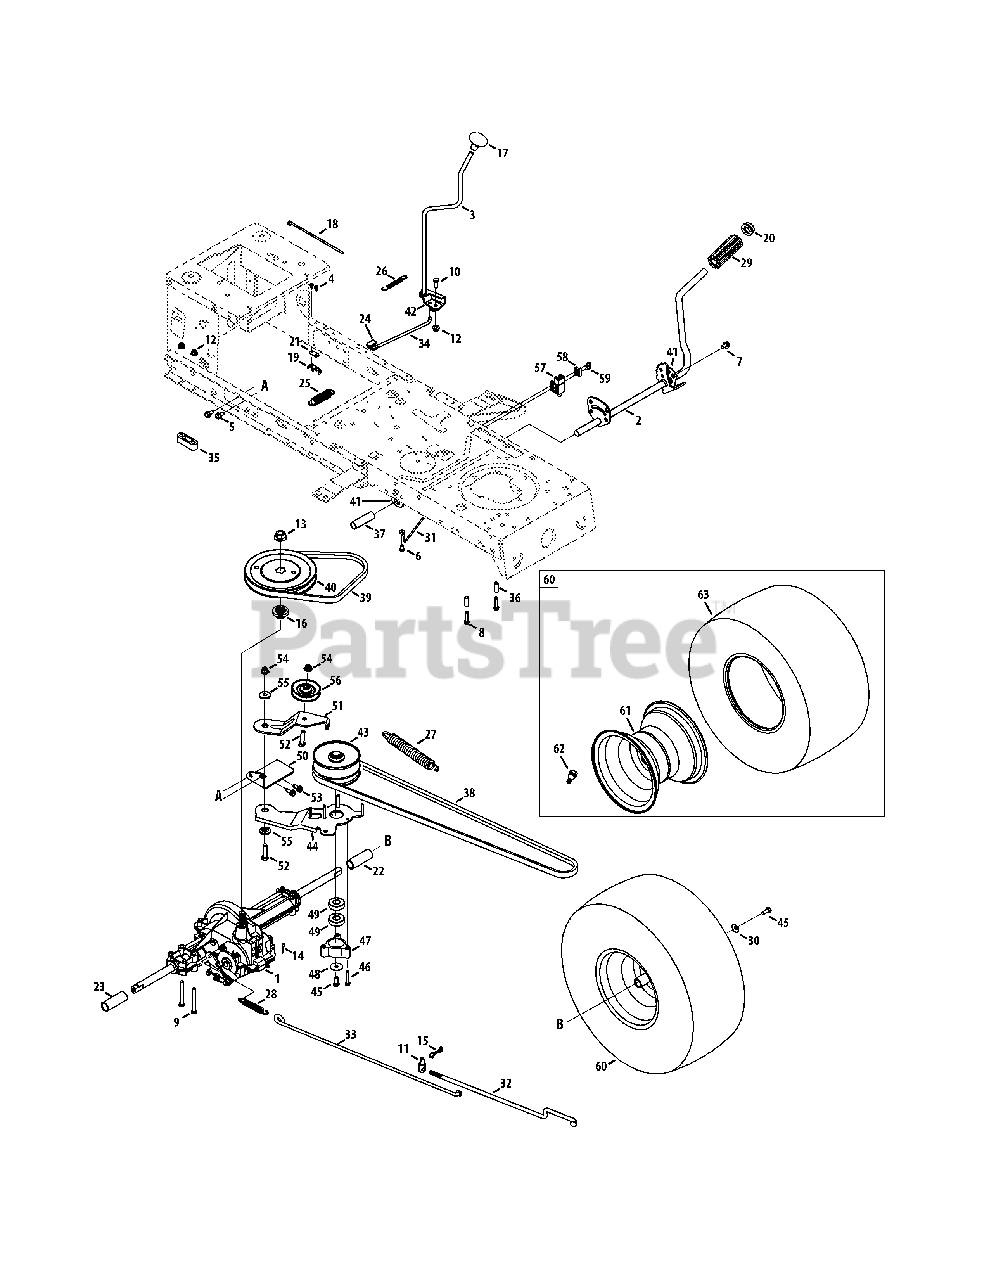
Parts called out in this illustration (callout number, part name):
1	Transmission Drive Assembly
2	Pedal Assembly
3	Shaft Lever Assembly
4	Screw, 8-18, 0.500
5	Screw, 5/16-18 x .750
6	Screw, 1/4-20 x 0.500
7	Screw, 5/16-18 x 0.625
8	Screw, 1/4-20 x 1.250
9	Hex Screw, 5/16-18 x .625
10	Hex Screw, 5/16-18 x .75
11	Ferrule, 3/8-24 X .375 DIA.
12	Flange Lock Nut, 5/16-18
13	Flange Nut, 9/16-18
14	Cotter Pin INT- .125 DIA
15	Bow-Tie Cotter Pin
16	Pulley Hub, 5/8 SPLINE
17	Shift Knob
18	Cable Tie
19	Short Spring Switch
20	Push Cap, 5/8
21	Plate Insulator Nut
22	Sleeve, .758 x .821 x 3.3125
23	Sleeve, .758 x .821 x 2.4375
24	Shift Bearing Plate
25	Spring Extension, .80 OD x 3.28 LG
26	Spring Extension, .38 OD x 3.25 LG
27	Spring Extension, .94 OD x 6.75 LG
28	Spring Extension, .59 OD x 4.00 LG
29	Foot Pad, 4.0 LONG
30	Bell Washer, .340 x .872 x .060
31	Belt Keeper Rod
32	Variable Speed Control Rod
33	Brake Rod
34	Shift Rod, 46"
35	Spacer, T-Axle
36	Spacer, .260 x .375 x 1.030 LG
37	Spacer, .640 ID x .76 OD x 2.63
38	V Belt, 5L, 70.90 POLY
39	V Belt, 5L, 33.80 POLY
40	Trans. Pulley
41	Pedal Support Bracket
42	Shaft Adjust Bracket
43	Variable Speed Pulley Assembly
44	Bracket Assembly
45	Hex Screw, 5/16-24 x .750
46	Screw, 1/4-20 x 1.500
47	Bearing Cup
48	Flat Washer, .330 x 1.25 x .06, HT
49	Ball Bearing, 17 x 40 x 12
50	Transmission Bracket Assembly
51	Idler Bracket Assembly
52	Hex Screw, 3/8-16 x 1.75
53	Screw, 5/16-18 x 0.750
54	Flange Lock Nut, 3/8-16
55	Shoulder Spacer, .625 ID x .169
56	Idler Pulley
57	Switch Interlock
58	Plate Switch
59	Shoulder Screw, #10-32 x .500
60	Wheel Assembly, 18 x 6.5
61	Rim Assembly
62	Valve Stem
63	Tire, 18 x 6.5 x 8 Sq. Sh.
